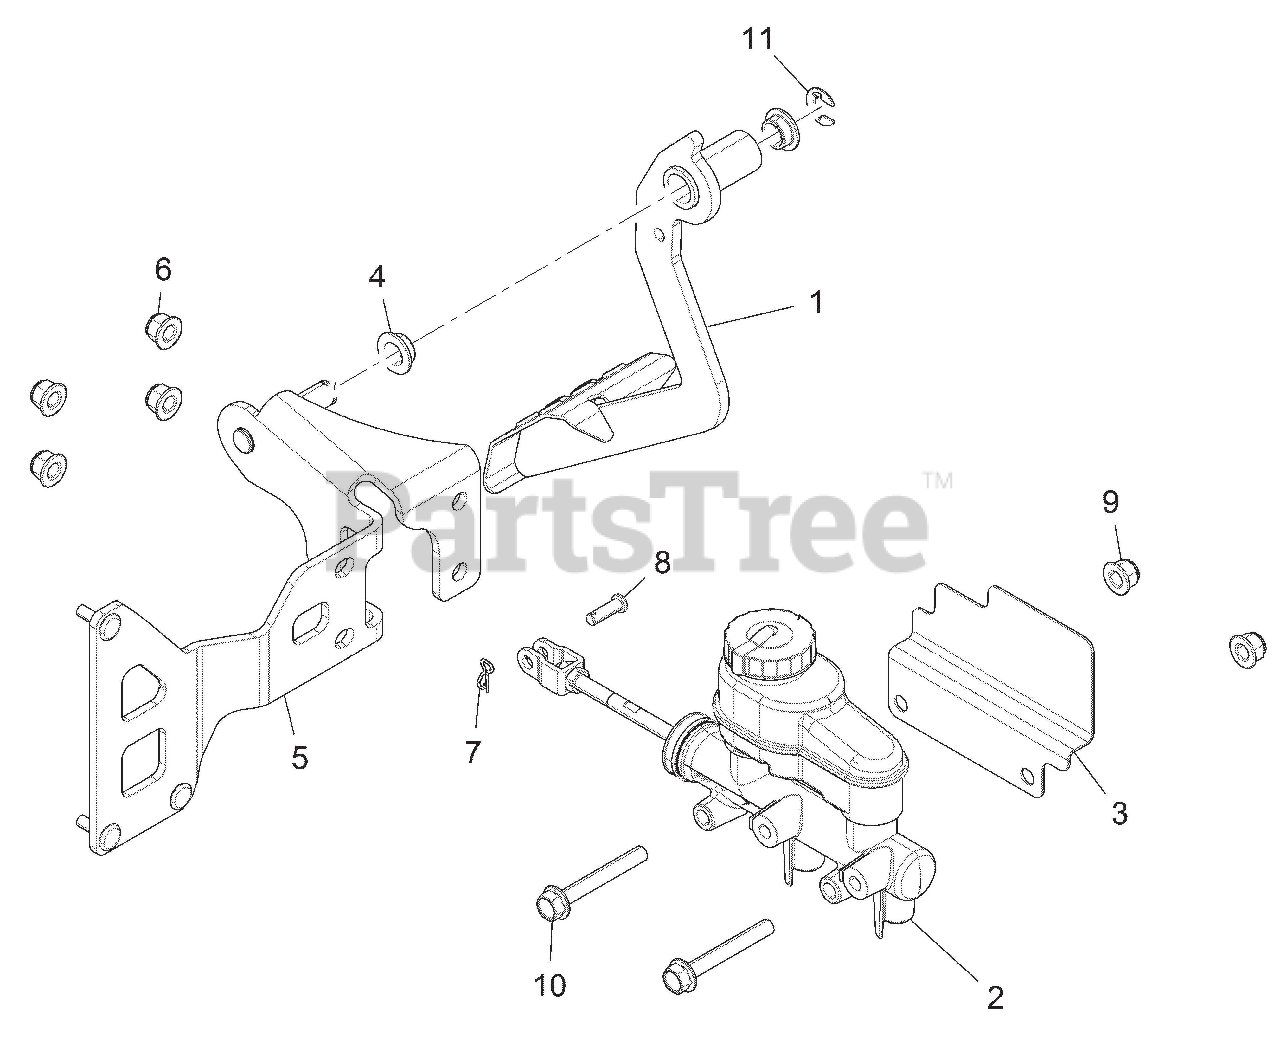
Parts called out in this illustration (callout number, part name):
1	WELD-BRAKE PEDAL,MATTE'BLK
2	ASM-MASTER CYLINDER,UV,GS
3	SHIELD-MASTER CYL
4	BUSHING-PEDAL PIVOT
5	WELD-PEDAL MOUNT,BLK
6	NUT-M8X1.25,FLG,NYLOC-OLIVE D
7	PIN-CLIP,14MM
8	PIN-CLEVIS, 1/4 X 3/4 -Y
9	NUT-M8X1.25,FLG,NYLOC-OLIVE D
10	SCR-HXFL-M8X1.25X60 8.8 ZOD
